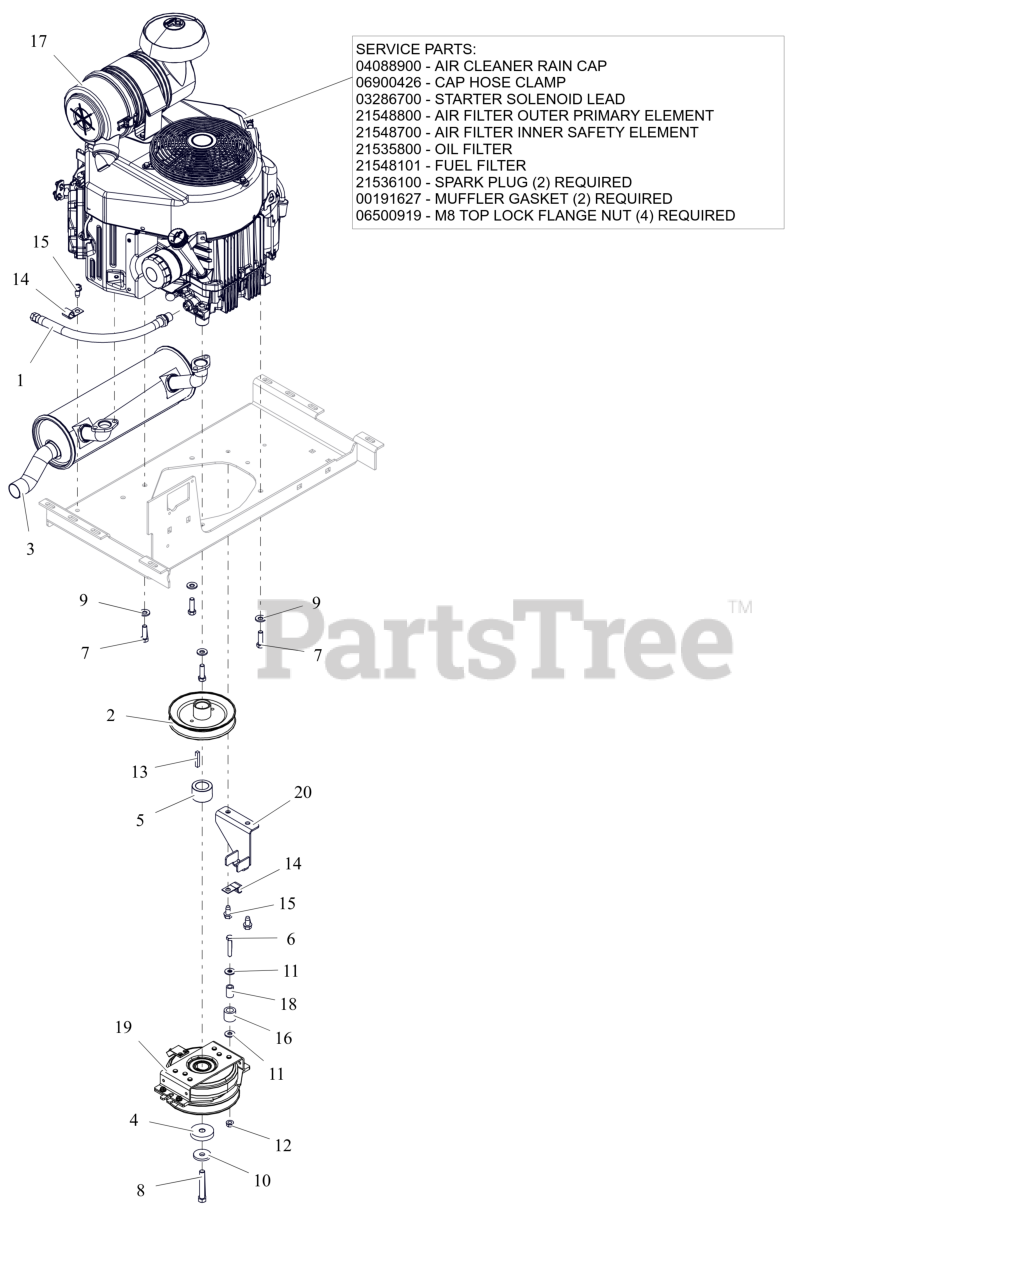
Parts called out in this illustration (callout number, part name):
1	HOSE, OIL DRAIN
2	WLDMT, TRANSAXLE DRIVE PULLEY
3	MUFFLER, KAW FX691/730
4	SPACER, .450X2.00X.396
5	SPCR, 1.125 x 1.750 x 1.147
6	BLT, HEX .31-18X1.75 G5 ZCC
7	BLT, HEX .38-16X1.25 G5 ZCC NT
8	BLT, HEX 0.4375-20X2.75 G8 ZCC NT
9	WASHER, 3/8" SPRING DISC
10	WASHER, 7/16" SPRING DISK
11	WSHR,FLT .375X.875X.083 ZCC
12	NUT,LK-CTR-FLG .31-18 GF ZCC
13	KEY-SQ .25 X 1.50 X .25 SAE
15	SCR,TAP .375-16X.75 HWH TR ZCC
16	BUMPER,RUBBER .62X1.0X.88 LG
17	ENGINE, KAWASAKI FX730
17	CAP, KAW 11065-7025
17	CLAMP, HOSE #36 SS 1.813-2.75
17	LEAD - STARTER SOLENOID
17	FILTER, OUTER
17	FILTER, INNER - KAW
17	FILTER,OIL - KAW
17	FUEL FILTER-KAWASAKI FR
17	PLUG, SPARK
17	GASKET, MUFFLER S/O
17	NUT-LK-TOP-FLG M8 ZCC
18	BUSH.,S.391X.622X.950 ST
19	CLUTCH- OGURA GT2.75-DC03(D)
20	BRKT- CLUTCH STOP - BLACK
